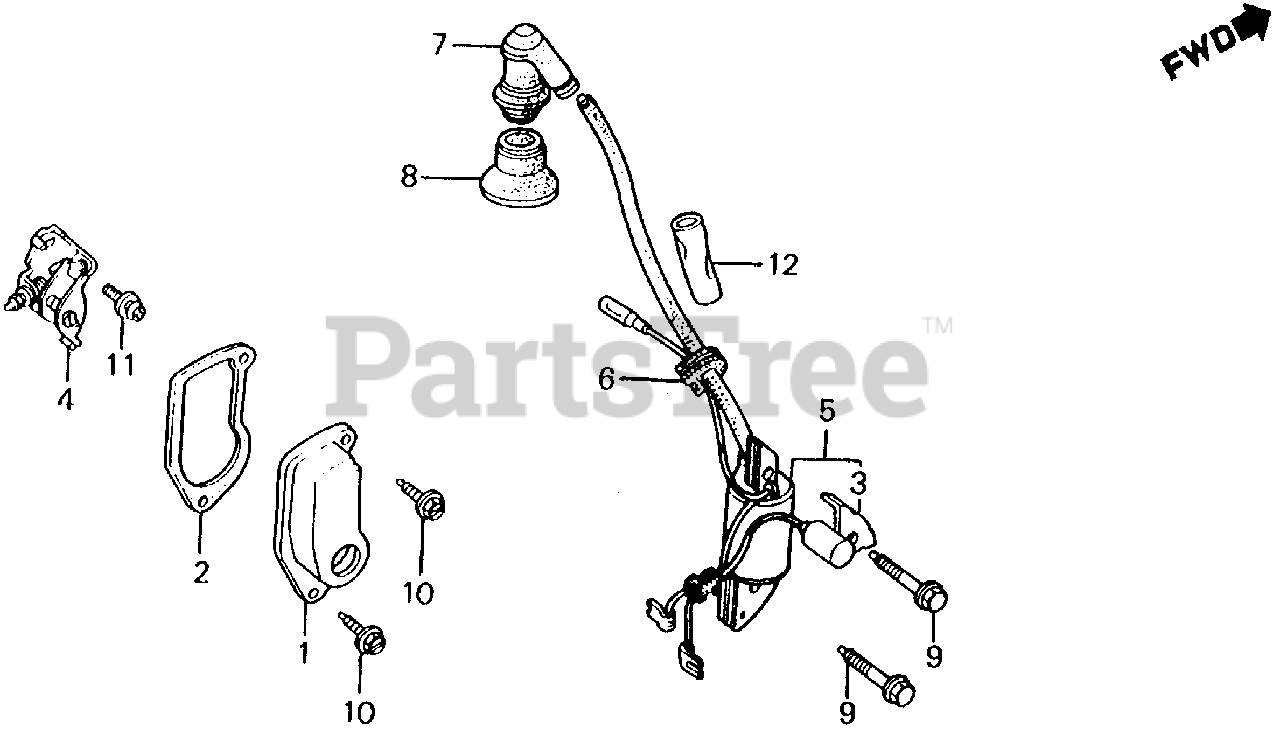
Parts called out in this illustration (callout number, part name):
1	COVER, POINTS
2	GASKET, POINT COVER
4	POINTS ASSY.
5	COIL ASSY., IGNITION
6	GROMMET, WIRE
7	CAP ASSY., NOISE SUPPRESSOR
8	SEAL, IGNITION
9	BOLT, FLANGE (6X32)
10	BOLT, FLANGE (5X10)
11	SCREW-WASHER (5X12)
12	TUBE, VINYL (12X16X50)
